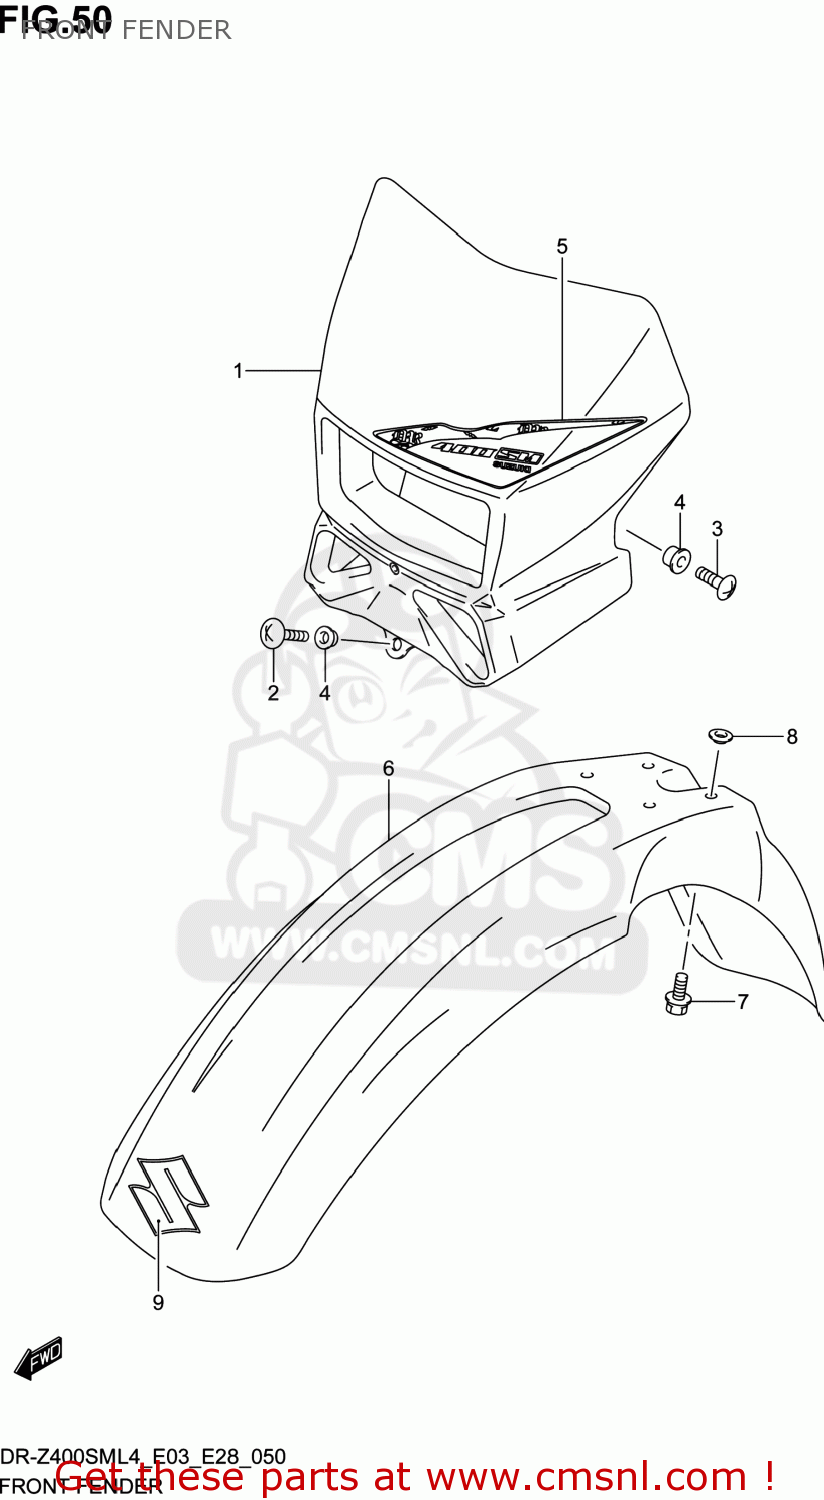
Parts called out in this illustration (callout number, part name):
1	COVER,HEADLAMP
2	SCREW
3	SCREW
4	WASHER
5	TAPE,HEADLAMP HOUSING
6	FENDER,FR
7	BOLT(6X16)
8	WASHER
9	EMBLEM,S
